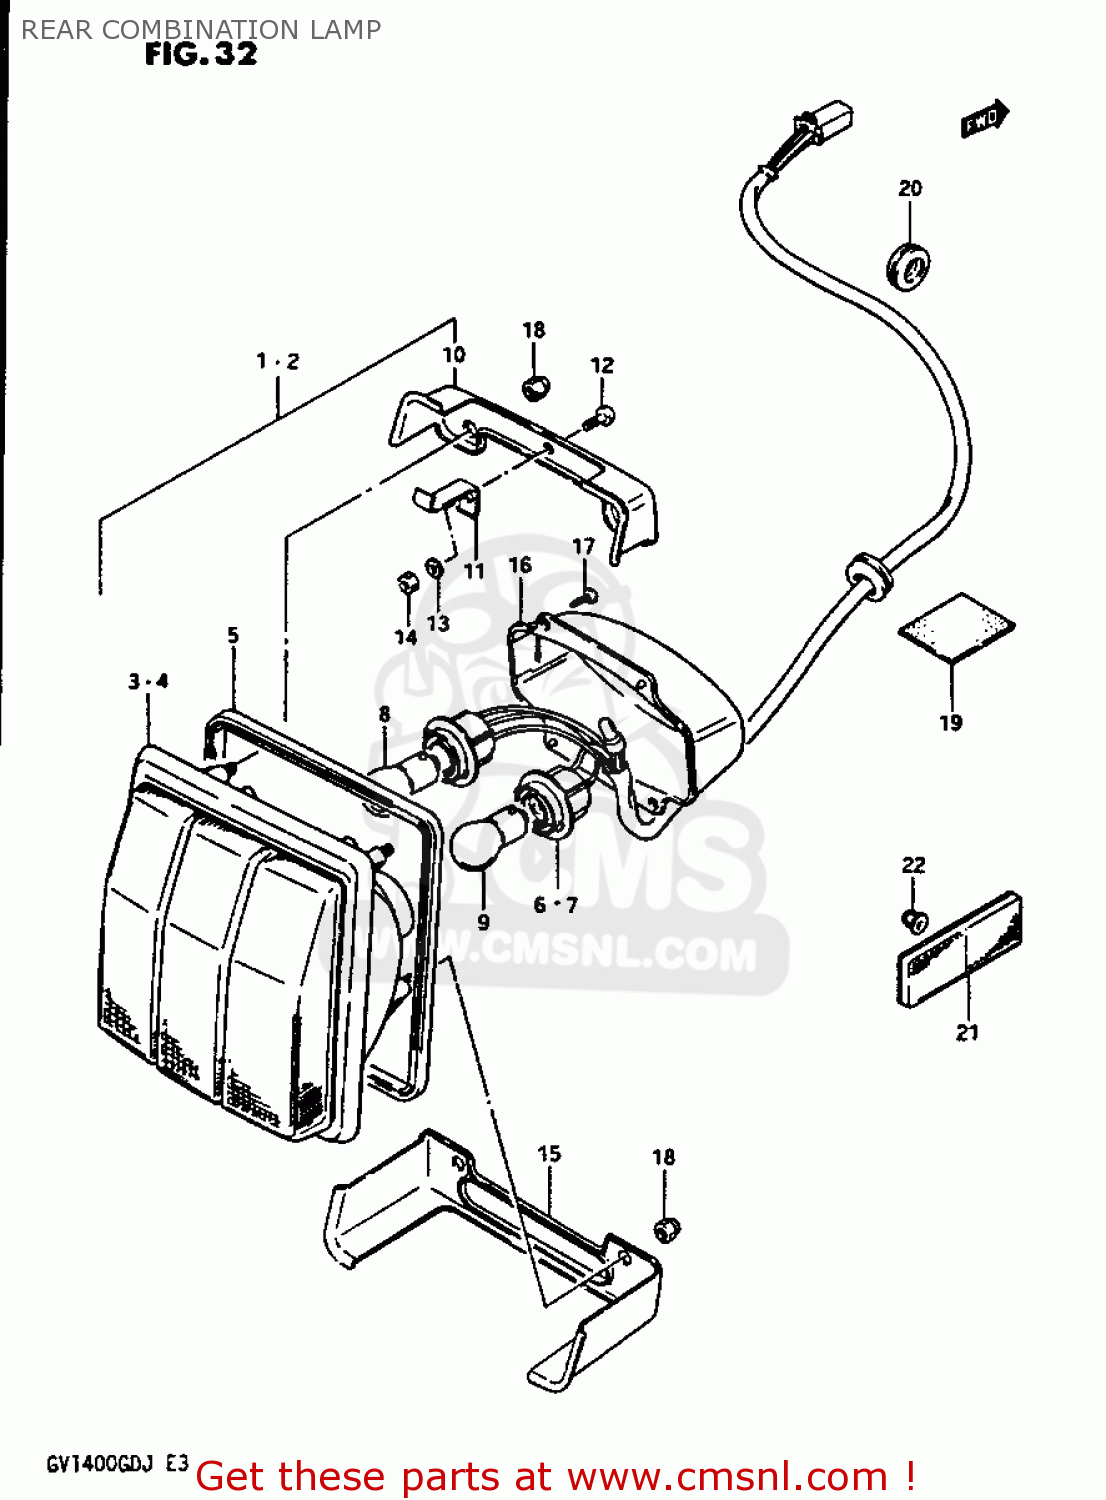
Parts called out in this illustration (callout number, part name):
1	LAMP ASSEMBLY,REAR COMBINATION
2	LAMP ASSEMBLY,REAR COMBINATION
3	LAMP UNIT,RIGHT
4	LAMP UNIT,LH
5	GASKET,REAR COMBINATION LAMP BASE
6	SOCKET,LEFT
7	SOCKET,LEFT
8	BULB(12V23/8W,TOKAI DENSO)
9	BULB(12V23W,STANLEY,A4577A)
10	BRACKET,REAR COMBINATION LAMP,UPPER
11	BRACKET, UPPER NO.2
12	SCREW
13	LOCK WASHER
14	NUT
15	BRACKET,REAR COMBINATION LAMP,LOWER
16	COVER
17	SCREW
18	NUT 6MM
19	COVER,HARNESS
20	GROMMET
21	REFLEX REFLECTOR ASSY,RR SIDE
22	NUT 5MM
